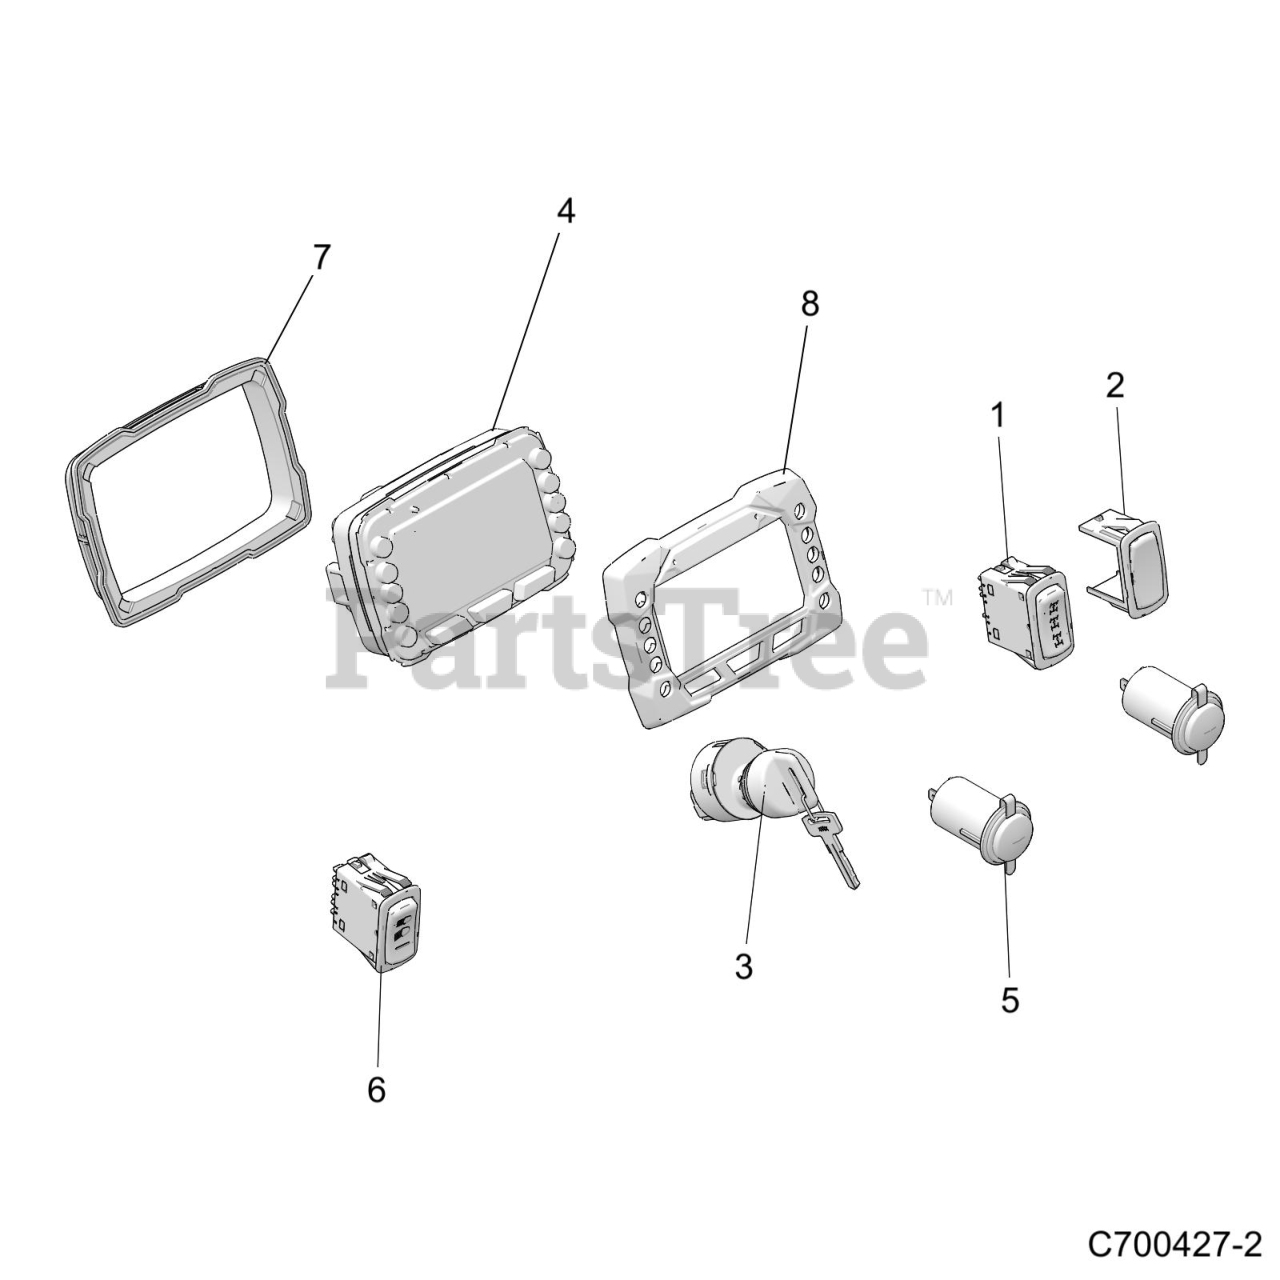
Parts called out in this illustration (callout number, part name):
1	SWITCH-AWD
2	SWITCH-PLUG,BLANK
3	SWITCH-KEY,COMMON,3POS,SEALED
4	ASM-CLUSTER,B1
5	RECEPTACLE-POD MNT,12 VOLT
6	SWITCH-HEADLIGHT
7	GASKET-DIGITAL GAUGE
8	BEZEL-GAUGE,B1,UNBRANDED
